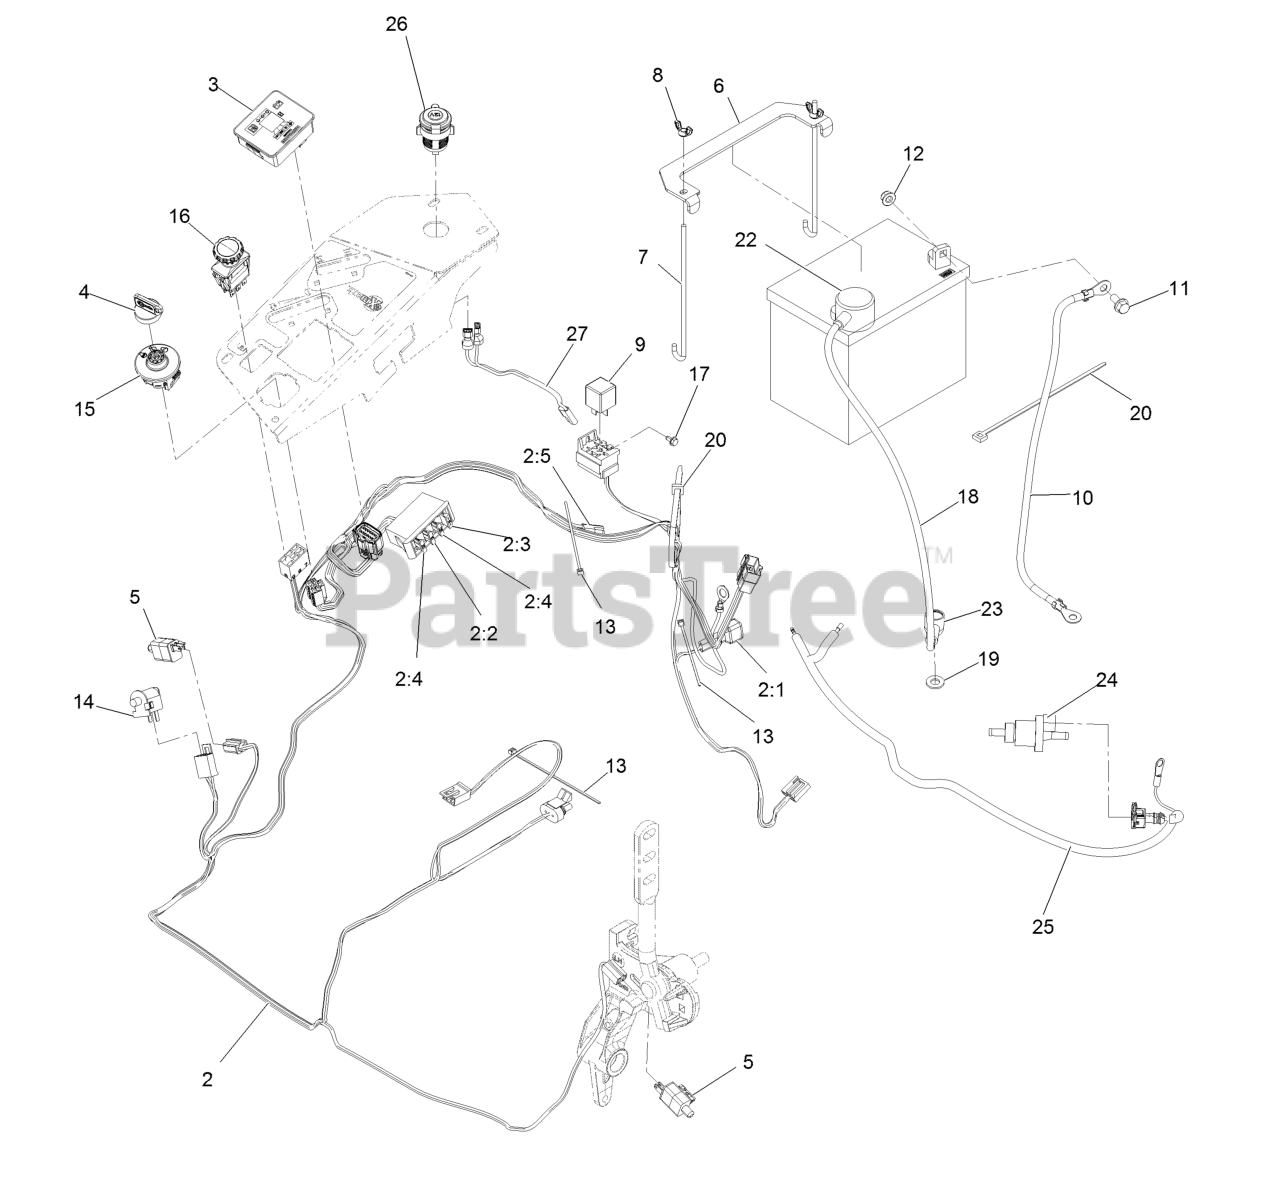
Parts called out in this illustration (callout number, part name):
2	HARNESS-WIRE, MAIN
2:2	FUSE-BLADE, 10 AMP
2:3	FUSE-BLADE, 15 AMP
2:4	FUSE-BLADE, 25 AMP
2:5	CAP-PLUG
3	FUEL/HOUR METER ASM
4	KEYS-IGNITION (SPARE PAIR
4	KEY-IGNITION
6	STRAP-TIE DOWN, BATTERY
7	BOLT-HOLDDOWN
8	WINGNUT
10	CABLE-BATTERY, NEGATIVE
11	SCREW-HHF
12	NUT-HF, NI
13	TIE-CABLE
14	SWITCH-BAIL
16	SWITCH-PTO, 10 AMP
17	SCREW-HWH
18	CABLE-BATTERY, POSITIVE
19	WASHER-FLAT
20	TIE-PLASTIC
22	INSULATOR-BATTERY
23	INSULATOR-SOLENOID
24	VALVE-PURGE
26	RECEPTACLE-12V
27	HARNESS, RECEPTACLE 12V
